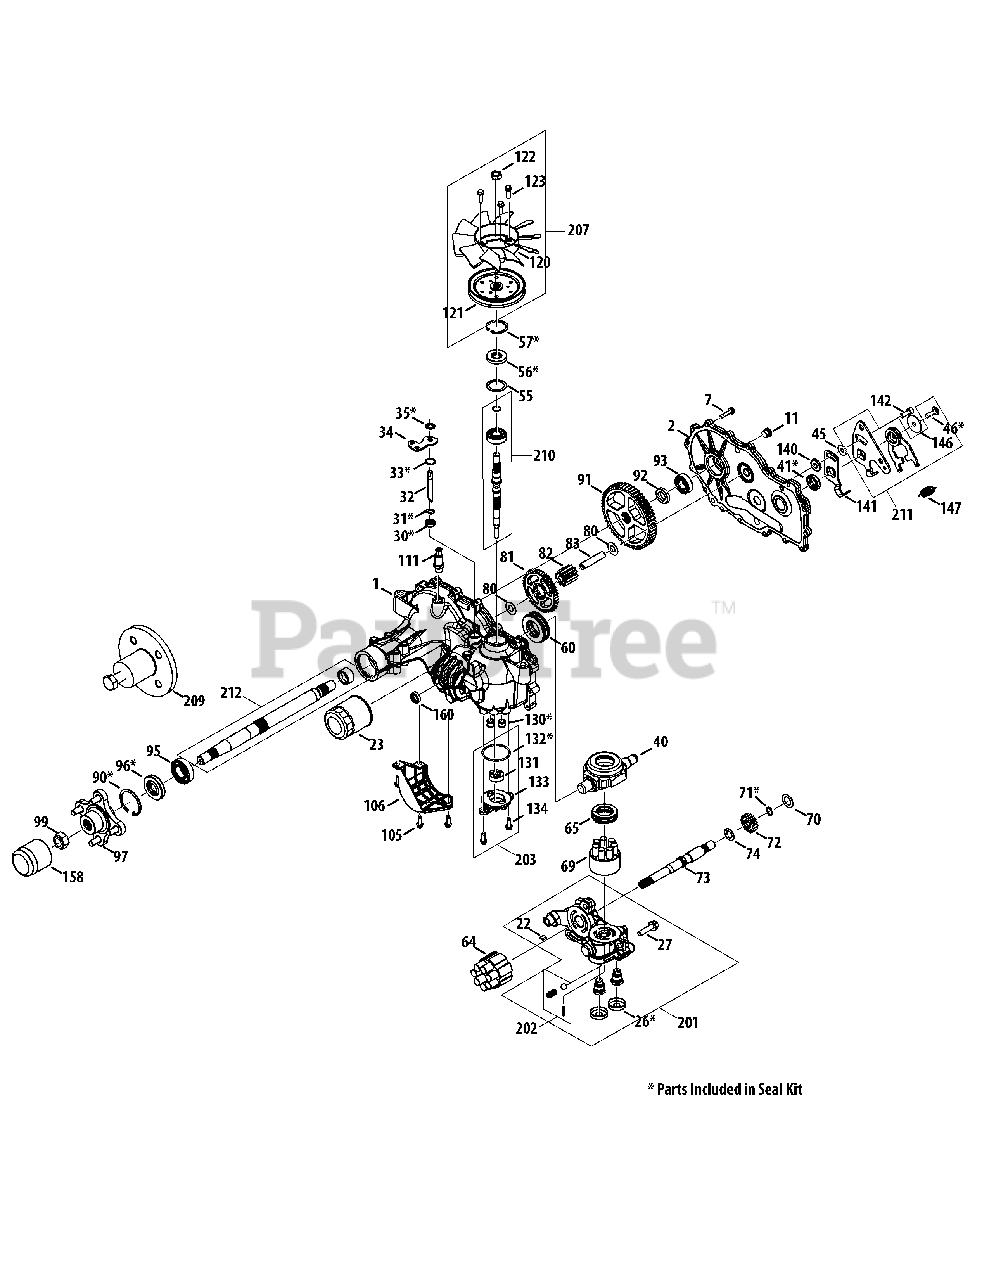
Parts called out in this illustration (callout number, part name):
1	Kit, Housing, Main, RH
2	Kit, Cover, Side, RH
7	Hex Cap Screw, 1/4-20 x 1.125
13	Sealant
22	Plate, Bypass
23	Oil Filter
26	Seal, Plug, 1.25 x .25
27	Hex Cap Screw, 3/8-16 x 1.5
30	Seal, Lip .375 x .75 x .25
31	Ring, Ret .375 External
32	Rod, Bypass
33	Ring, Ret .75 Internal
34	Arm, Bypass
35	Ring, Retaining .375 External
40	Trunnion, Swashplate
41	Seal, Lip 12 x 32 x 7
45	Washer, .34 x .88 x .06
46	Hex Cap Screw, 5/16-24 x 1.00
55	Washer, 1.23 x 1.56 x .04
56	Seal, Lip 17 x 40 x 7
57	Ring, Retaining
60	Bearing, Thrust
64	Cylinder Block Assembly
65	Thrust Ball Bearing, 30 x 52 x 13
69	Block 7 Piston Assembly
70	Washer, .63 x 1.0 x .05
71	Retaining Ring, .625
72	Gear, 14t
73	Motor Shaft
74	Washer, .72 x 1.16 x .04
80	Washer, .5 x 1.0 x .03
81	Gear, 45t
82	Gear, 11t
83	Jack Shaft
90	Retaining Ring, 2.06 Internal
91	Gear, 54t
92	Spacer, .75 x 1.32 x .257
93	Ball Bearing, .75 x 40 x 12
95	Ball Bearing, 1.0 x 52 x 15
96	Seal, Lip 25 x 52 x 10
97	Kit, Hub, 4 Bolt
99	Nut, 3/4-16, Hex Lock
105	Hex Cap Screw, 1/4-20 x .75
106	Guard, Filter, RH
111	Fitting, 9/16-18 SAE .5 Barb
120	Fan 7", 10 Blade
121	Disc, Pulley
122	Nut, 1/2-20, Hex Jam
123	Hex Cap Screw, 1/4-20 x .875
130	Connecting Tube
131	Gerotor Assembly
132	O-Ring, -137, .103 x 2.050
133	Charge Pump Cover
134	Hex Cap Screw, 1/4-20 x .75
140	Spacer, .320 x 1.005 x .179
141	Neutral Left Arm
142	Hex Cap Screw, 5/16-24
146	Washer, .343 x 1.5 x .062
147	Extension Spring, .57 x 2"
160	Seal, Lip, .625 x .875 x .25
201	Kit, Center Section, RH
202	Kit, Charge Relief
203	Kit, Charge Pump
207	Kit, Fan & Pulley
209	Hub Puller, 4 Bolt
210	Kit, Input Shaft
211	Kit, RTN, Bidirectional
212	Kit, Shaft, Axle
